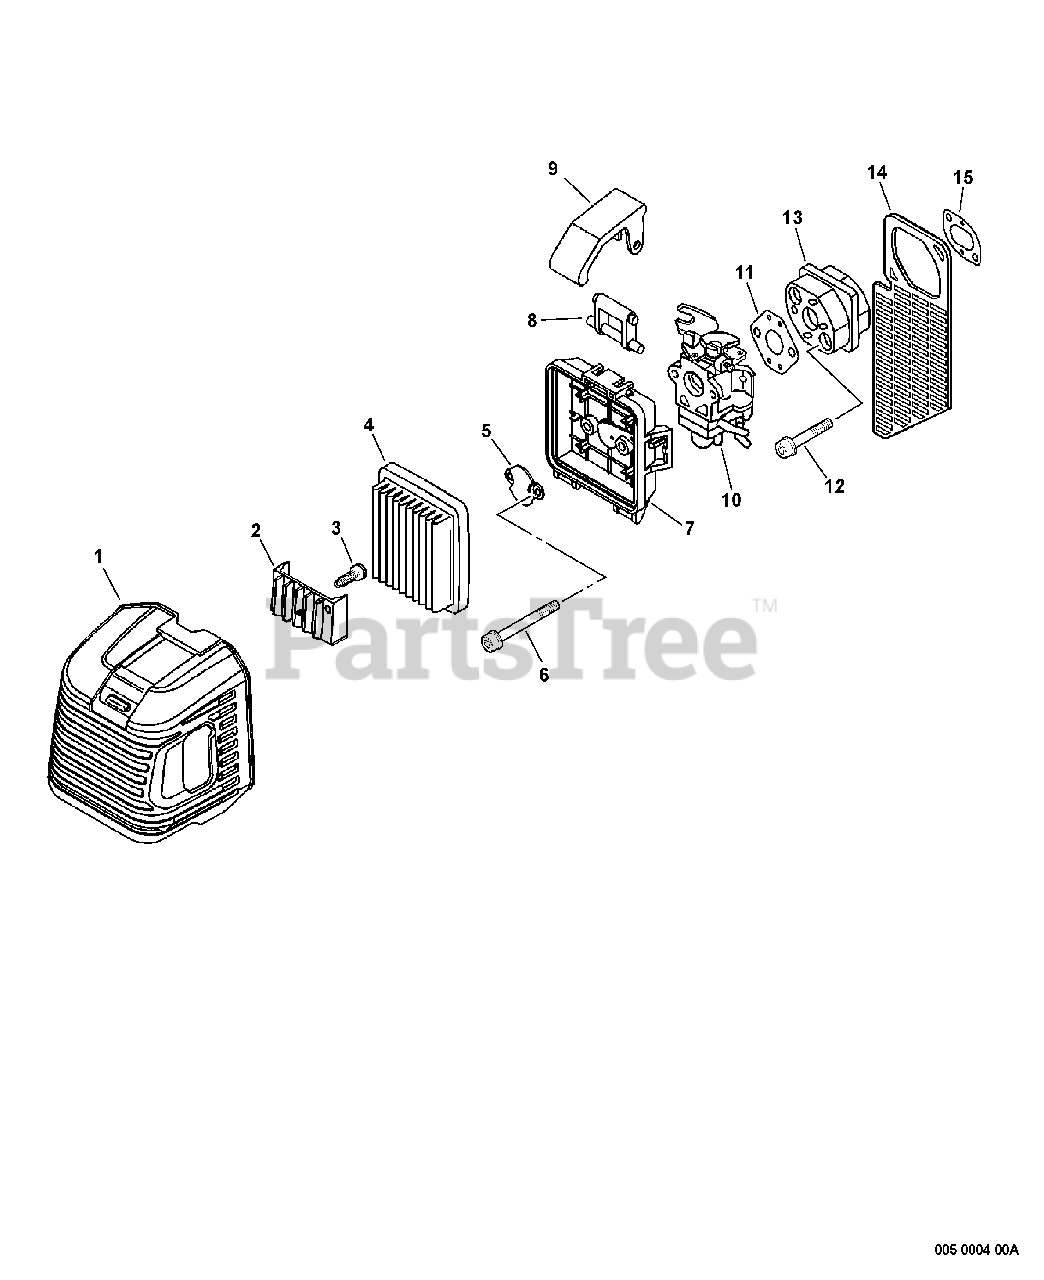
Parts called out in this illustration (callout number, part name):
1	COVER, AIR FILTER
2	PIECE, COVER
3	SCREW - 4X8
4	FILTER, AIR
5	PLATE, PREVENT
6	SCREW - 5X55
7	CASE, AIR FILTER
9	LATCH, CLEANER LID
10	CARBURETOR
11	GASKET, INTAKE
12	SCREW - 5X25
13	INSULATOR, INTAKE
14	GUARD, DEBRIS
15	GASKET, INTAKE
